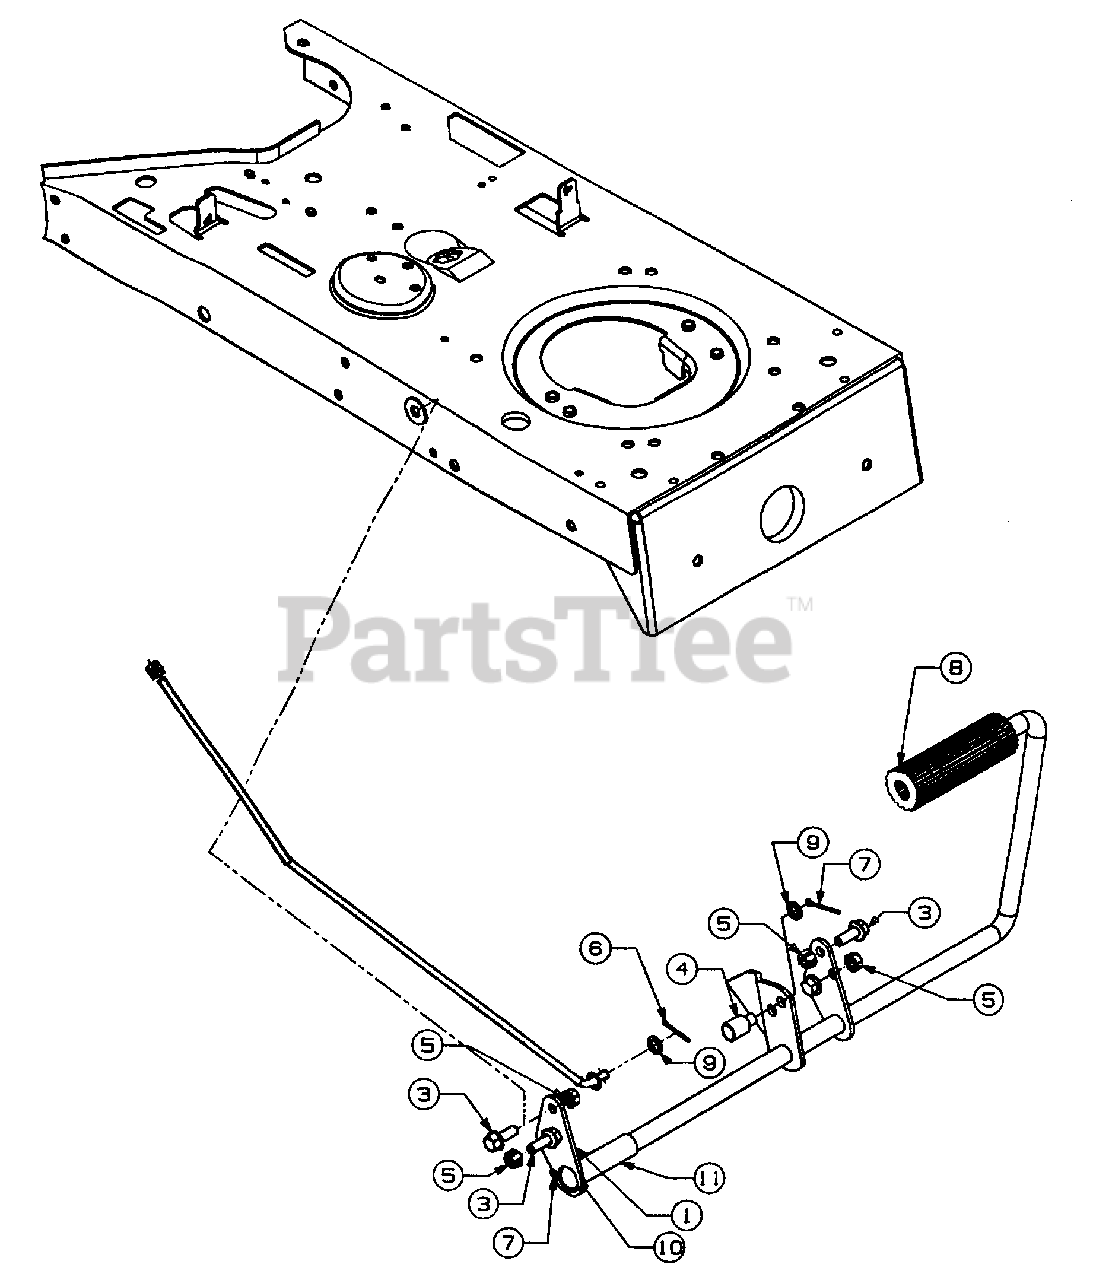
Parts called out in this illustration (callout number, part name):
4	Ferrule 3/8-24 Thd.
5	Hex Sems Nut 5/16-18 Thd.
6	Cotter Pin 3/32" Dia. x 1" Lg.
7	Cotter Pin 1/8" Dia. x 1.25" Lg.
8	Foot Pad
9	FL-Wash. .385" I.D. x .62" O.D.
10	FL-Wash. .63" I.D. x .93" O.D.
11	Spacer .64" I.D. x 2.63" Lg.
